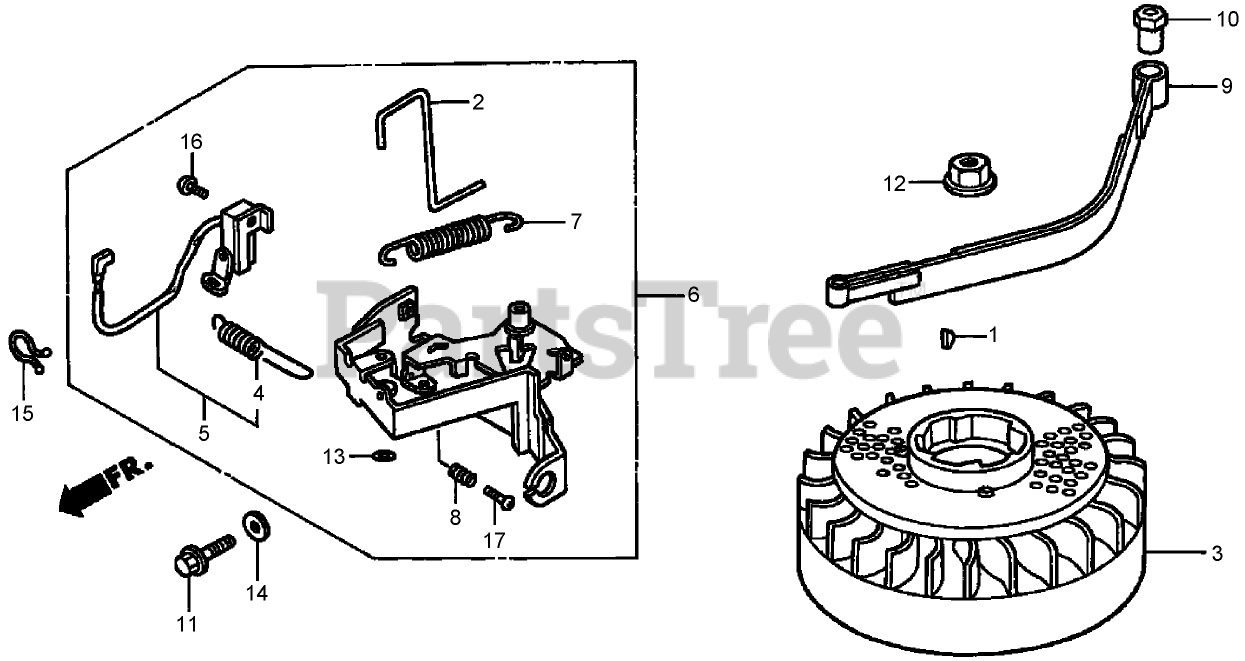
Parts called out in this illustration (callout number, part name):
1	KEY-WOODRUFF, SPECIAL (25X18)
2	Rod-Governor Arm, Return
3	Flywheel Asm
4	Spring-Switch, Control
5	Engine Stop Switch Asm
6	Brake Lever Asm
7	Spring-Brake, Lever
8	Spring-Brake, Adjusting
9	Brake
10	Collar-Brake, Shaft
11	BOLT-FLANGE (6X14) (C T200)
12	NUT-SPECIAL (14 mm)
13	Nut-Push (2.6)
14	Washer-Sealing (6.5X12)
15	Clip-Purse, Lock
16	Screw-Pan (4X8)
17	Screw-Pan (5X12)
